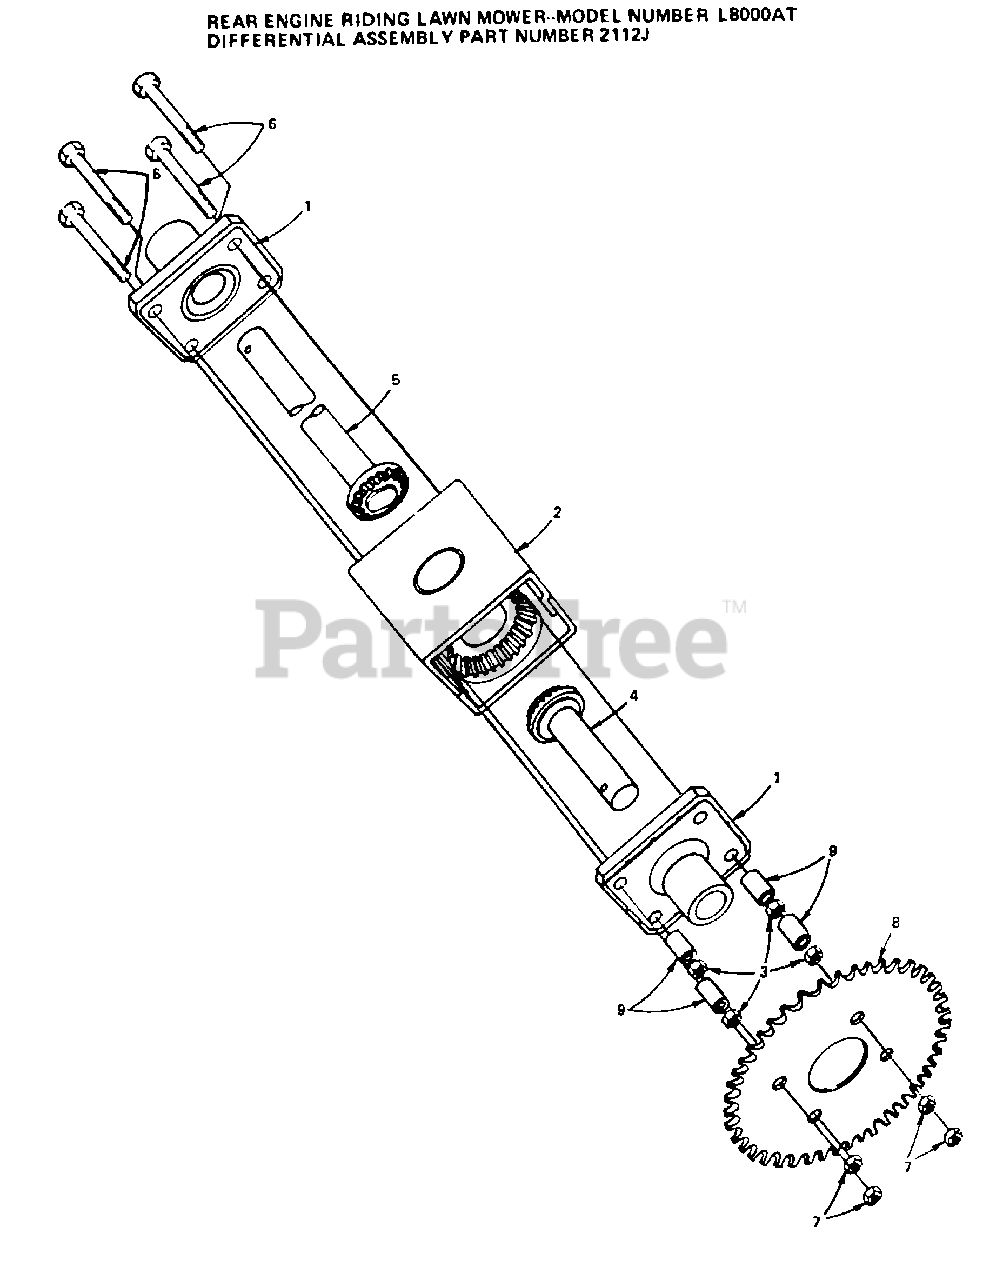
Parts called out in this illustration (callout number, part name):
1	CAPBEAR ASSY
2	TRANSFER GEAR CASE ASSY
3	NUT.HEX.5/16-18
5	GEAR SHAFT L RE
6	BOLT
9	SPACKER - SPROCKET
